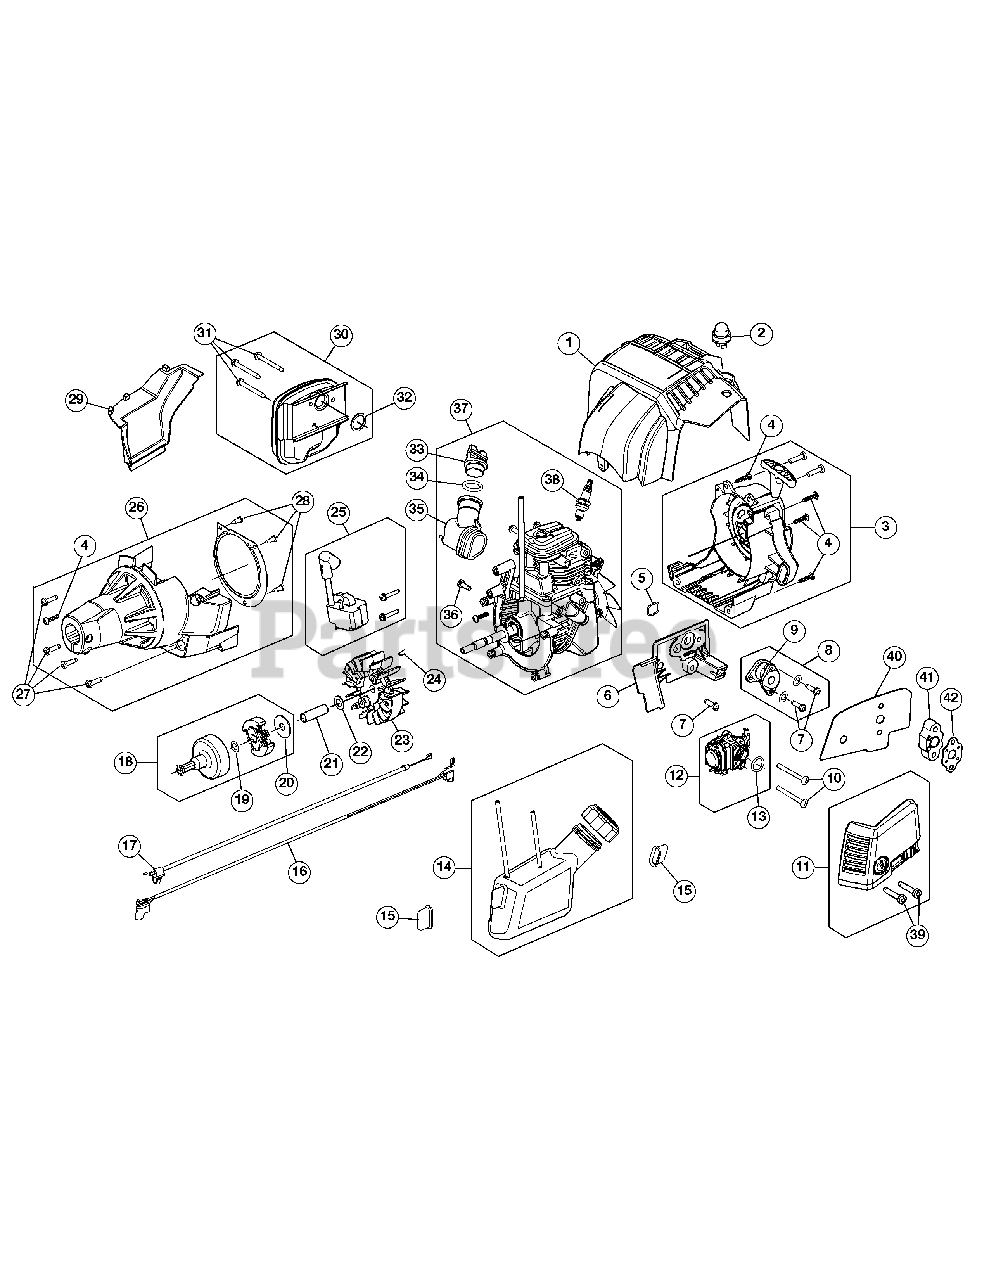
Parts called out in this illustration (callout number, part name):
1	Top Housing
2	Air Purge Primer
3	Starter Housing Assembly (Incl. 4)
5	O-Ring
6	Intake Port
7	Screw
8	Boot Assembly (Incl. 8 & 10)
9	Boot
11	Air Cleaner Assembly
12	Carburetor Assembly (Incl. 13)
14	Fuel Tank Assembly
15	Fuel Tank Pad
16	Lead Wire
17	Throttle Cable
18	Clutch Assembly (Incl. 19 & 20)
19	Thrust Washer
20	Clutch Washer
21	Spacer
22	Washer
23	Flywheel
25	Module Assembly
26	Clutch Cover Assembly (Incl. 27 & 28)
28	Screw
29	Rear Engine Cover
30	Muffler Assembly (Incl. 31 & 32)
31	Screw
32	Muffler Gasket
33	Oil Fill Plug
34	O-Ring
35	Oil Fill Tube Assembly
36	Screw
37	Shortblock Assembly (Incl. 38)
38	Spark Plug
40	Carburetor Gasket
41	Insulator
42	Insulator Gasket
